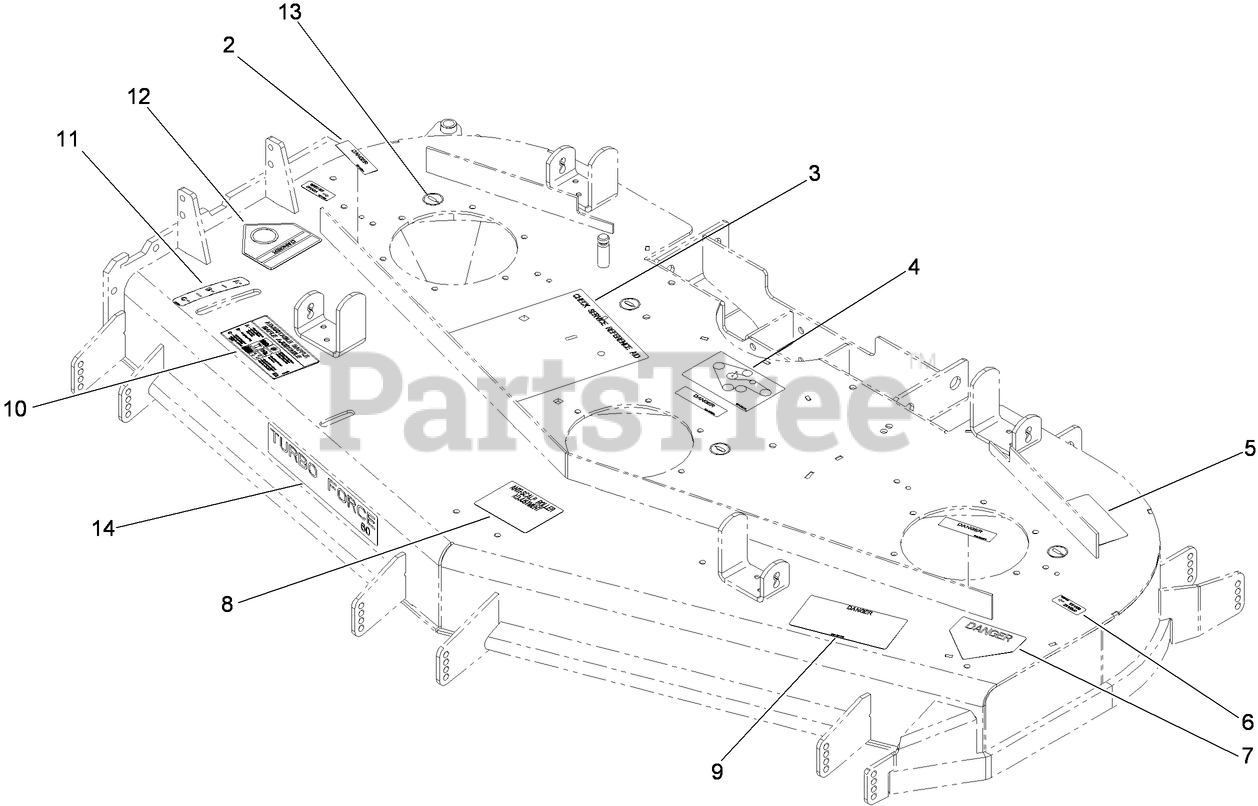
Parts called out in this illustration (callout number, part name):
2	DECAL-COVER, MISSING
3	DECAL-CHECK, SERVICE
4	DECAL-ROUTING, BELT
5	DECAL-TORQUE
6	Decal-Grease
7	DECAL-DANGER
8	DECAL-SCALP, ANTI
9	DECAL-DANGER, THROWN OBJECT
10	DECAL-ADJUSTMENT, BAFFLE
11	DECAL-SETTING, BAFFLE
12	DECAL-DANGER
13	DECAL-GREASE
